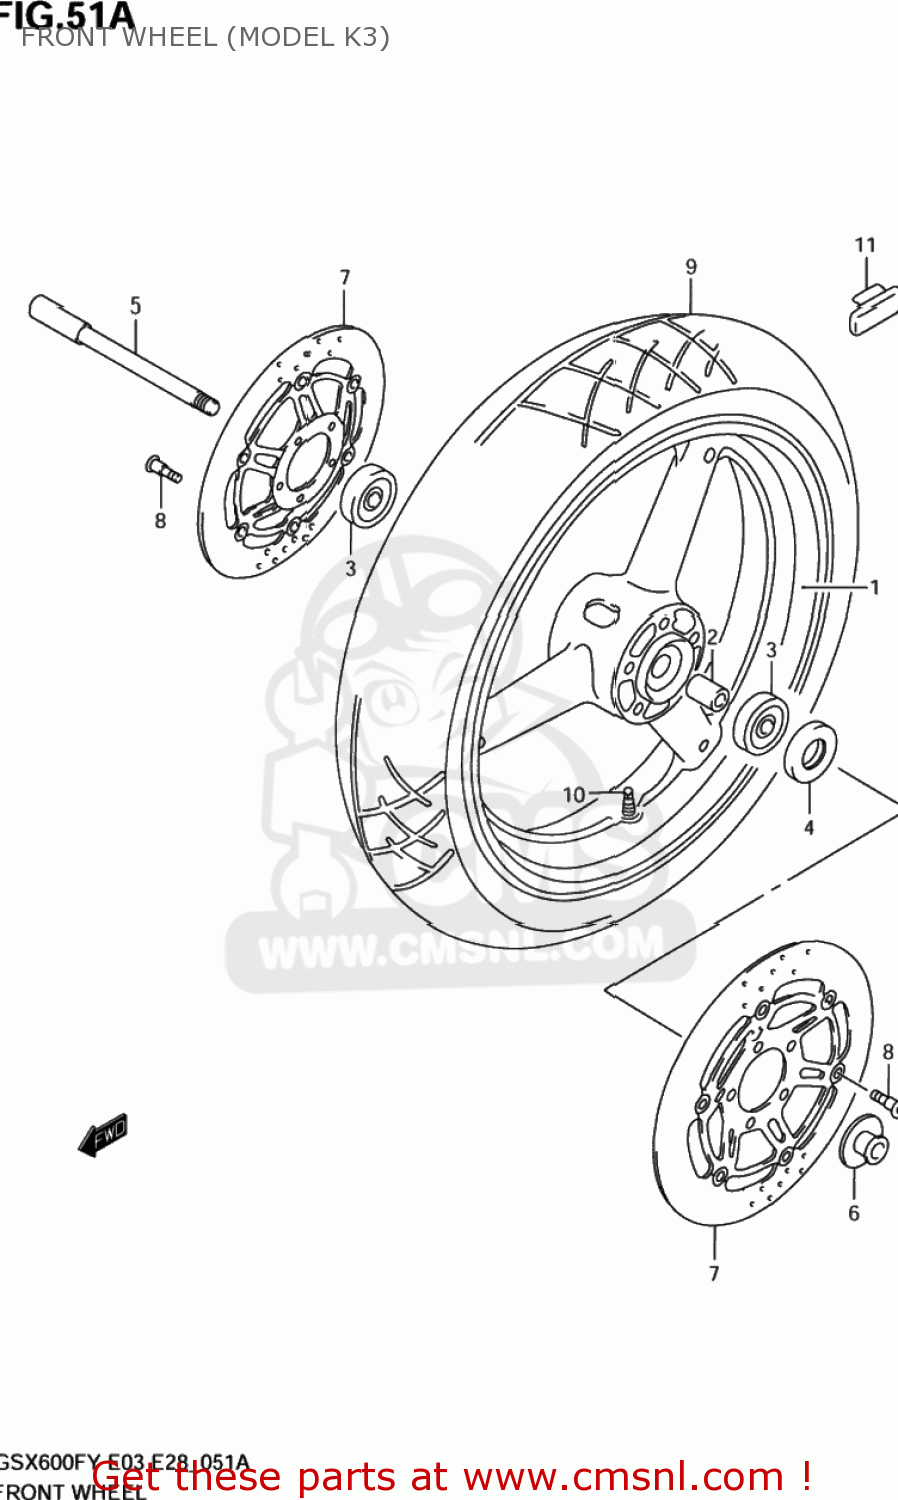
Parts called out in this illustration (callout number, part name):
1	WHEEL,FR(17M/CXMT3.50)
2	SPACER(17.5X25X88)
3	BEARING
4	SEAL,OIL(22X40X7)
5	AXLE,FR
6	SPACER,FR AXLE,L
7	DISC,FRONT BRA
8	BOLT(8X21)
10	VALVE ASSY,WHEEL RIM(TR412)
11	BALANCER,WHEEL (10G)
